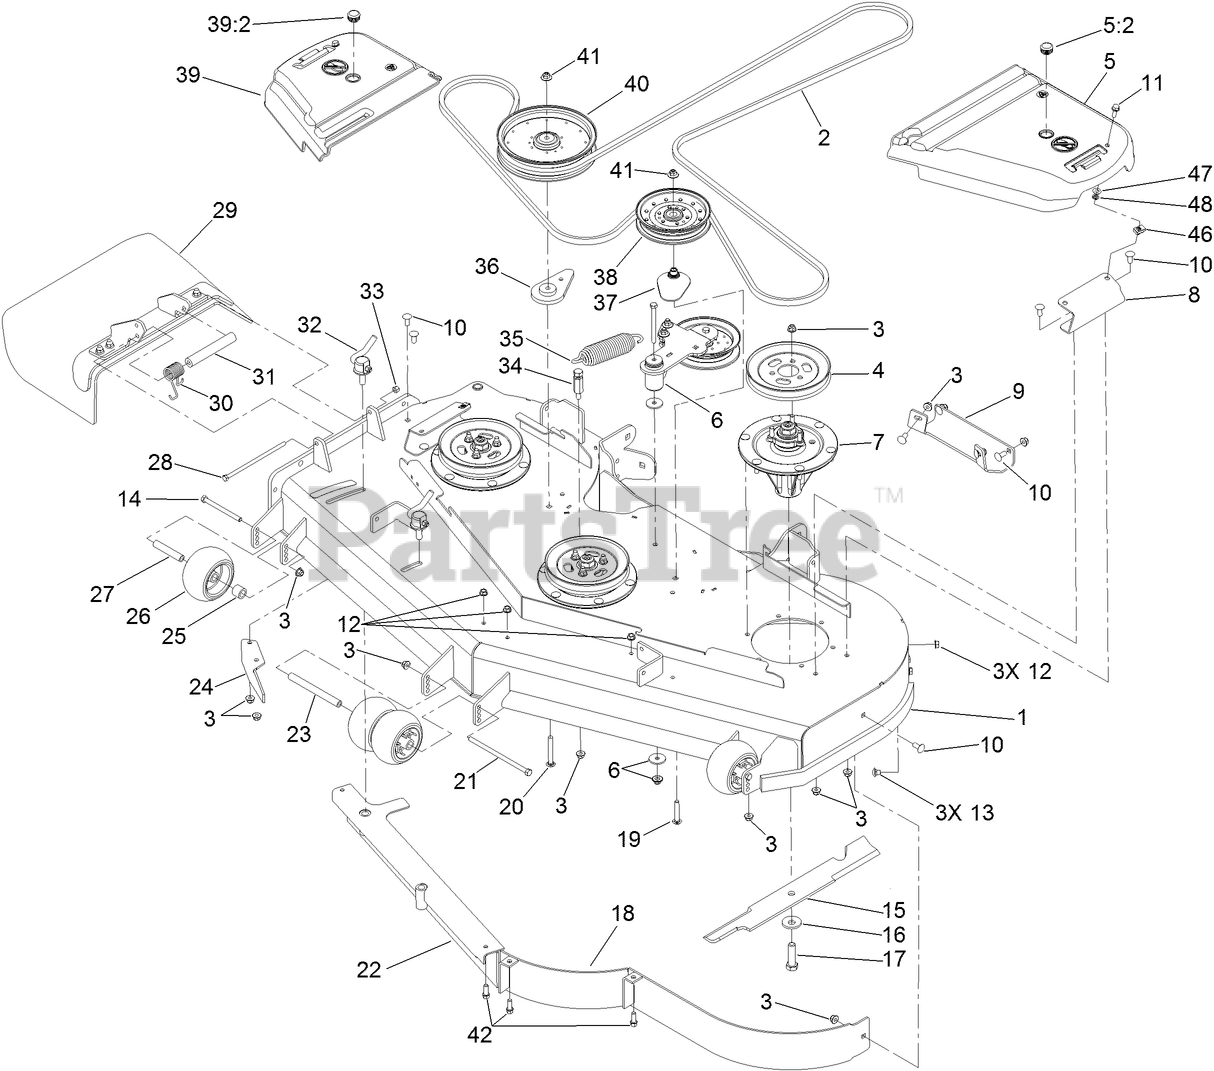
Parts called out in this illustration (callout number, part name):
1	DECK DECAL ASM
2	BELT-V
3	NUT-HF, NI
4	Pulley
5	LH BELT COVER ASM
5:2	PLUG-PLASTIC
6	IDLER ARM ASM
7	SPINDLE ASM
8	BRACKET-COVER, BELT
9	Plate-Skid
10	SCREW-CARR
11	SCREW-HHF
12	NUT-HHF, WHIZ
13	SCREW-CARR
14	SCREW-HH
15	BLADE-HI FLOW
16	Washer-Blade Bolt, Heavy
17	SCREW-BLADE
19	BOLT-CARR, SHORT NECK
20	SCREW-CARR
21	SCREW-HH
23	SPACER-WHEEL
24	BAFFLE-DISCHARGE
25	TUBE-SPACER
26	ROLLER-SCALP, ANTI
27	TUBE-SPANNER
28	SCREW-HH
29	RUBBER DEFLECTOR ASM
30	SPRING-TORSION
31	SPACER
32	LEVER ASM
33	NUT-LOCK, NI
34	ANCHOR-SPRING, TALL
35	SPRING-EXTENSION
36	SPACER-IDLER
37	SPACER-PULLEY
38	PULLEY-IDLER, FLAT
39	RH BELT COVER ASM
39:2	PLUG-PLASTIC
40	PULLEY-IDLER
41	NUT-FLANGE, NI
42	SCREW-HWH
46	NUT-U
47	WASHER-THRUST
48	NUT-PUSH
